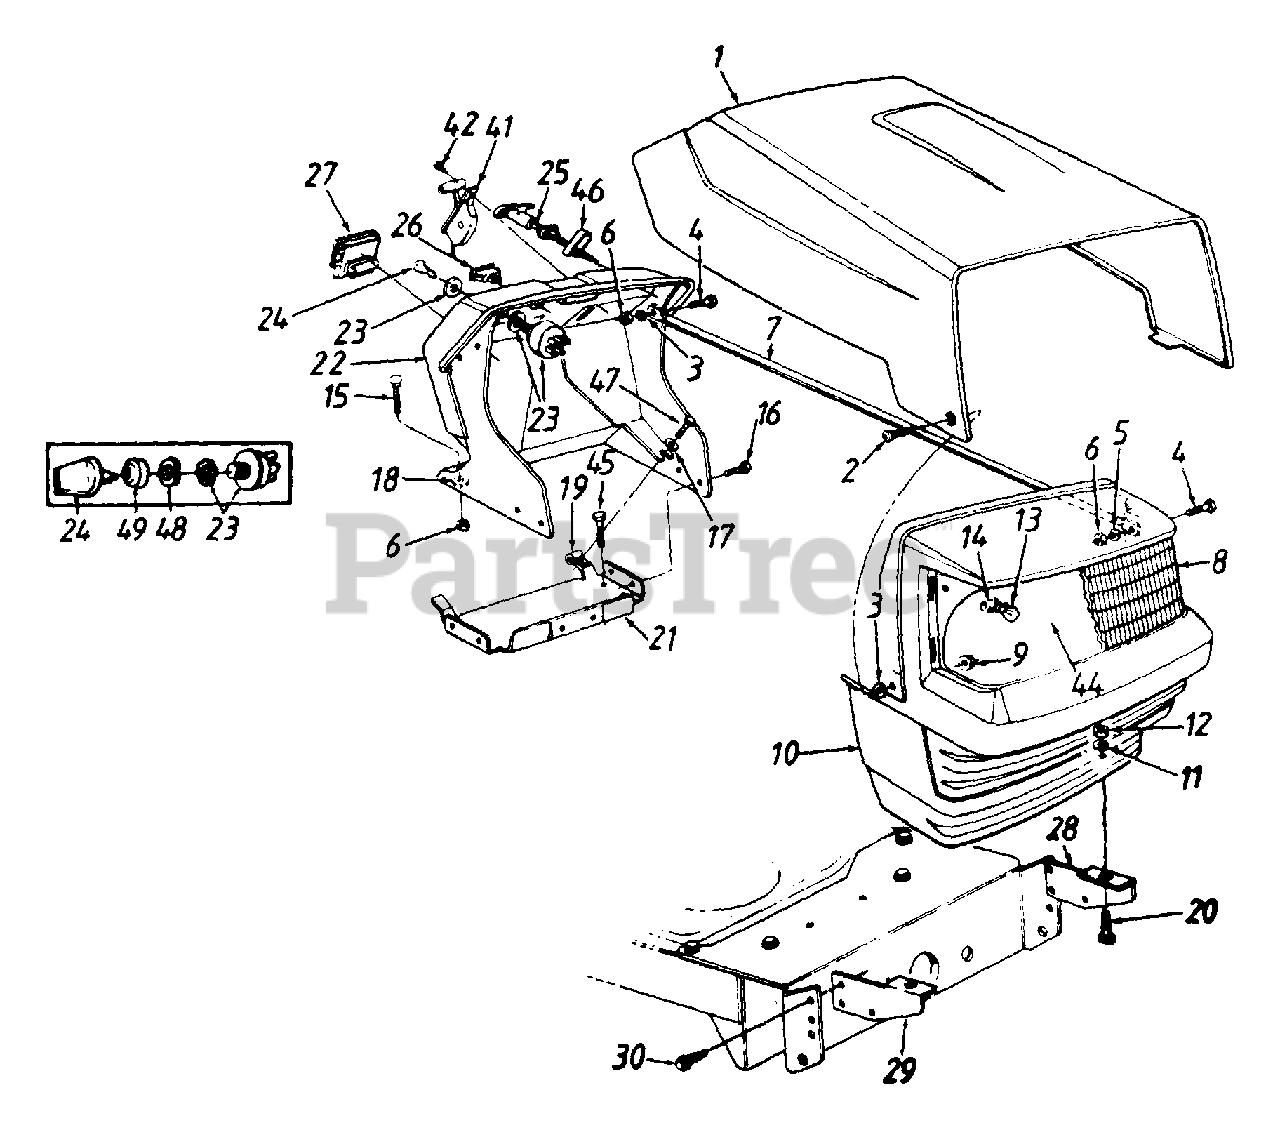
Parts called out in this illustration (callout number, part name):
3	Fl-Wash..28" I.D. x .75" O.D.
4	Hex Bolt 1/4-20 x .62" Lg.
5	L-Wash. 1/4" I.D.
6	Hex Nut 1/4-20 Thd.
8	Headlight Lens
9	Flange L-Nut 1/4-28 Thd.
10	Grille
11	L-Wash. 5/16" I.D.
12	Hex Nut 5/16-18 Thd.
13	Lamp
14	Socket
15	Carriage Bolt 1/4-20 x .75" Lg.
16	Hex Wash. Hd. TT-Tap Scr. 1/4-20 x .5" Lg.
17	Fl-Wash..281" I.D. x.73" O.D.
18	Bolt Retainer 1/4" I.D.
19	Speed Nut 1/4-20 Thd.
20	Hex Bolt 5/16-18 x .75" Lg.
21	Gas Tank Support Brkt.
22	Dash w/Ammeter hole
23	Ignition Switch
24	Ignition Key
25	Choke Controls
26	Light Switch
27	Ammeter
28	Grille Mtg. Brkt.- L.H.
41	Throttle Box Ass'y.
42	Truss Mach. AB-Tap Scr. #10 x .5" Lg.
44	Grille Reflector Label
45	Hex Wash. Hd. B-Tap Scr, 5/16-18 x .5" Lg.
46	Choke Retainer
47	Hex TT-Tap Scr. 1/4-20 x .75" Lg.
48	Ignition Switch Nut
49	Ignition Switch Cap
